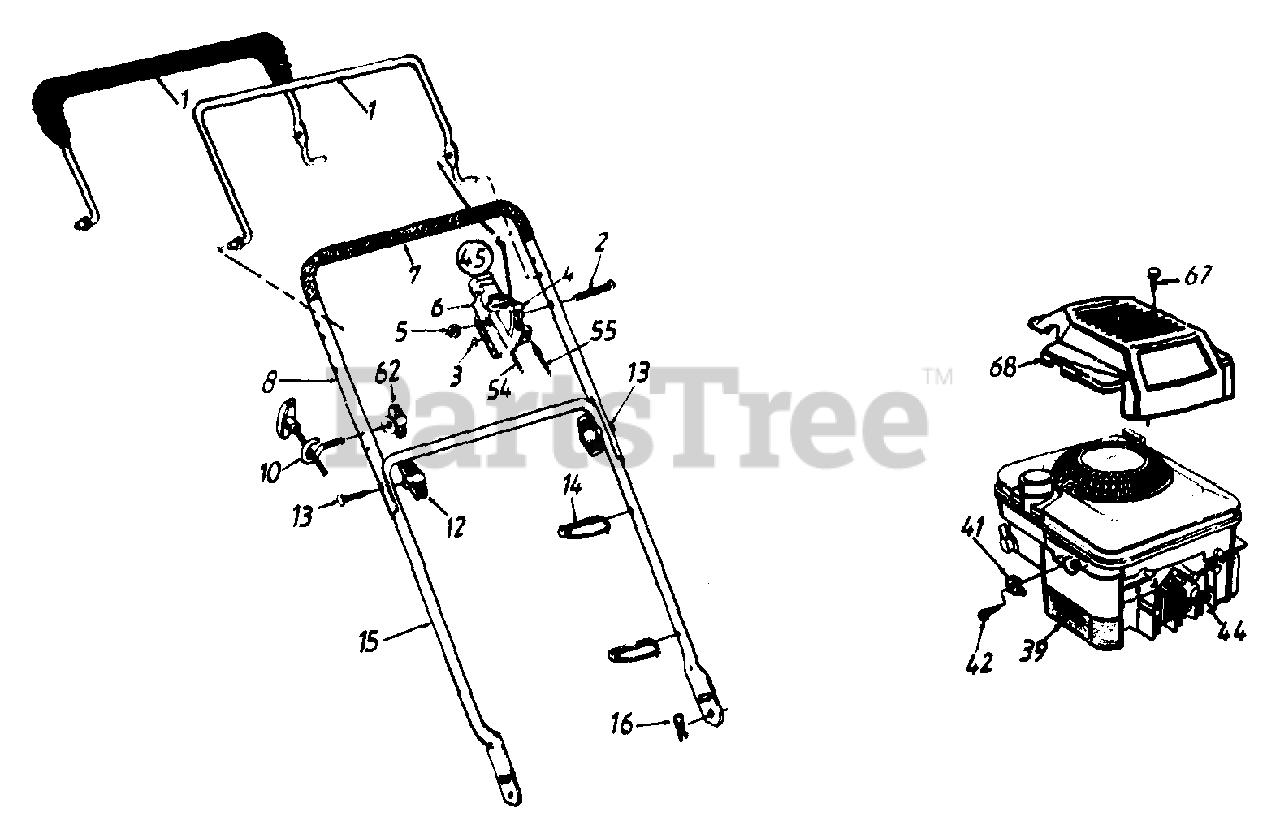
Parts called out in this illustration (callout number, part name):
1	Control Handle Ass'y. (106F)
2	Oval C-Sunk Scr.
3	Spr. Wash..66" I.D.
4	Throttle Lever
5	Hex L-Nut 1/4-20 Thd.
6	Throttle Body
7	Grip (106F)
12	Hand Knob
13	Curved Hd. Bolt 5/16-18 x 2" Lg.
14	Cable Tie
16	Hairpin Cotter
39	Engine
41	Cable Clamp
42	Hex Self-Tap Scr. #10-32 x .62"
44	Spark Plug Boot
45	Throttle Box Comp.
54	Throttle Cable - 51" Lg.
55	Control Cable - 36" Lg.
62	Handle Knob 1/4-20 Thd.
67	Hi-Lo Scr. #10 x 1.25" Lg. (106F)
68	Engine Shroud (106F)
